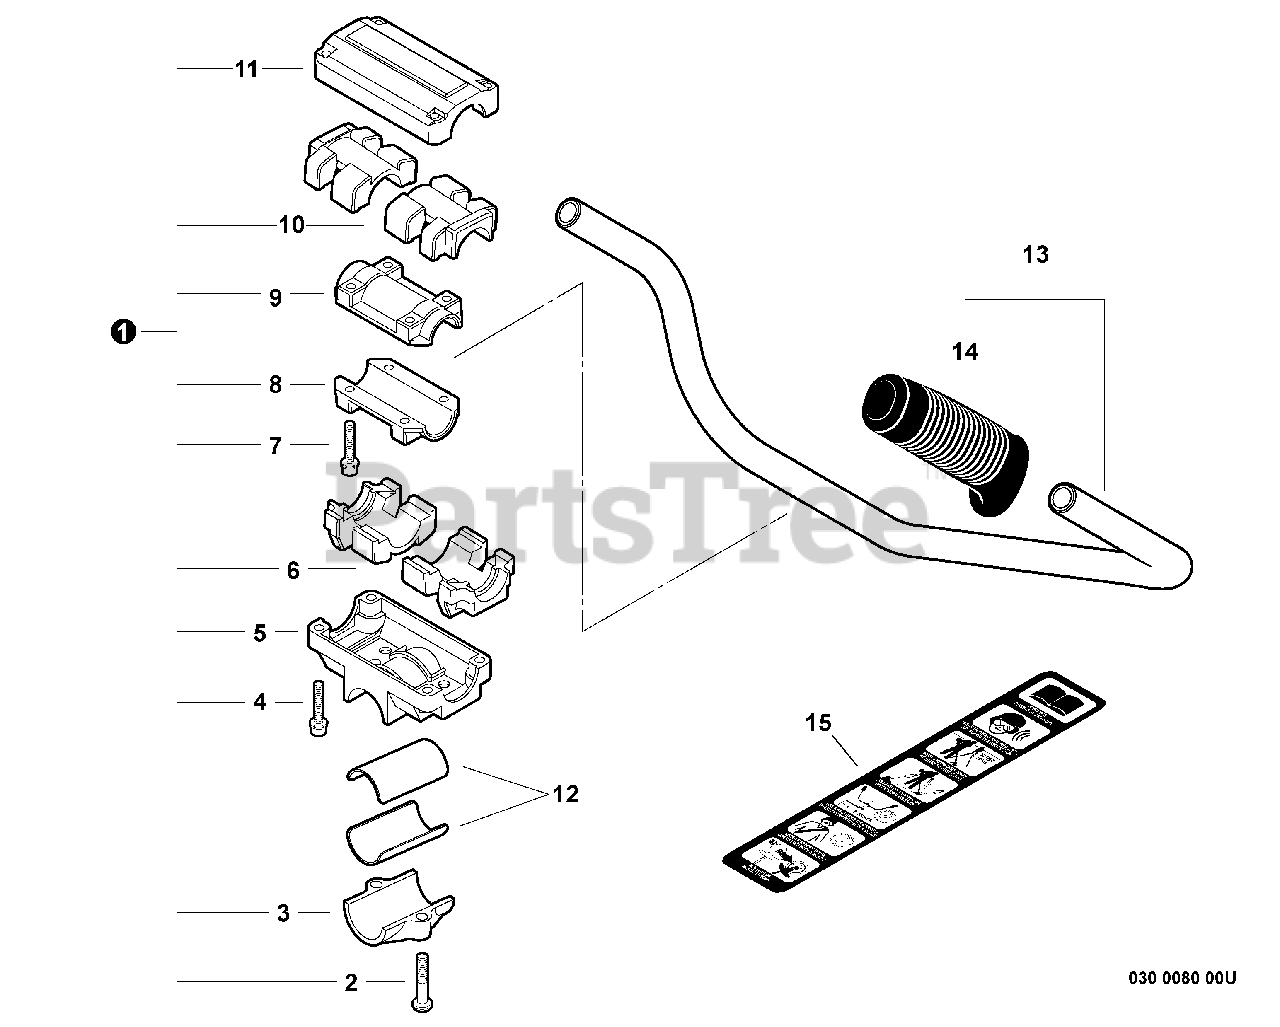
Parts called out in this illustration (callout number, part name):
1	HANDLE BRACKET KIT
2	SCREW - 6X25
3	BRACKET, MOUNTING
4	SCREW - 5X25
5	BRACKET, HANDLE - LOWER
6	CUSHION - LOWER
7	SCREW - 5X25
8	CLAMP - LOWER
9	CLAMP - UPPER
10	CUSHION - UPPER
11	BRACKET, HANDLE - UPPER
13	HANDLE ASSY
15	LABEL - CAUTION
